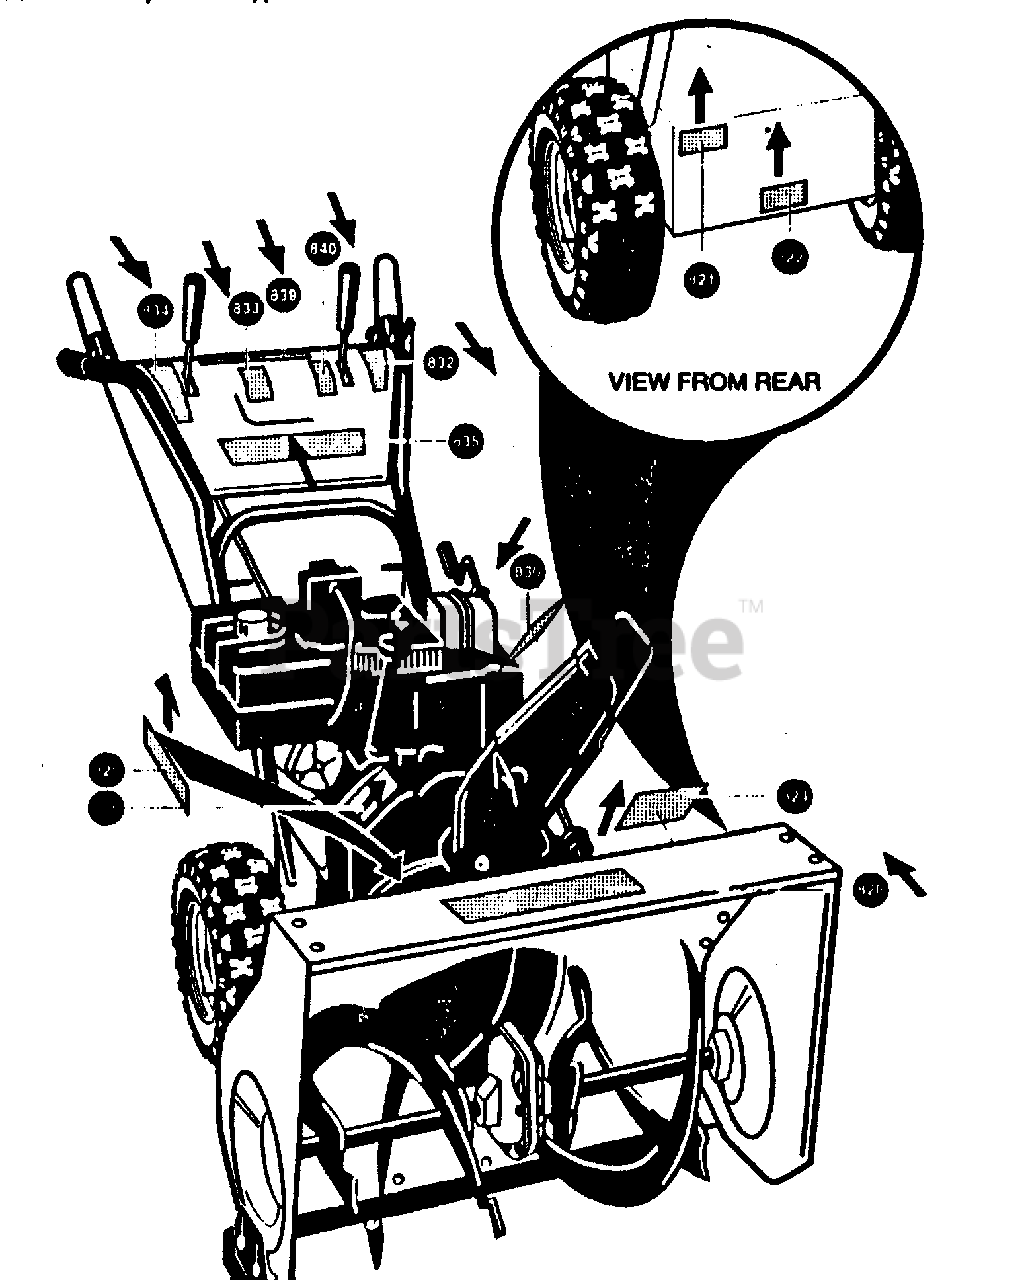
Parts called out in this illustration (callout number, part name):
821	NOT A SERVICABLE PART
822	DECAL, OVER ADJ OF DISC
824	DECAL, DANGER AUGER
825	DECAL, DANGER
826	DECAL, ST927E
830	DECAL, DANGER CHUTE
832	DECAL, TRACTION DRIVE
833	DECAL, SNOW CONDITIONS
834	DECAL, GEAR SELECT
835	DECAL, CONTROL PANEL
838	DECAL, BELT STRETCH & ADJ
839	DECAL, SINGLE HAND
840	DECAL, CHUTE CONTROL
